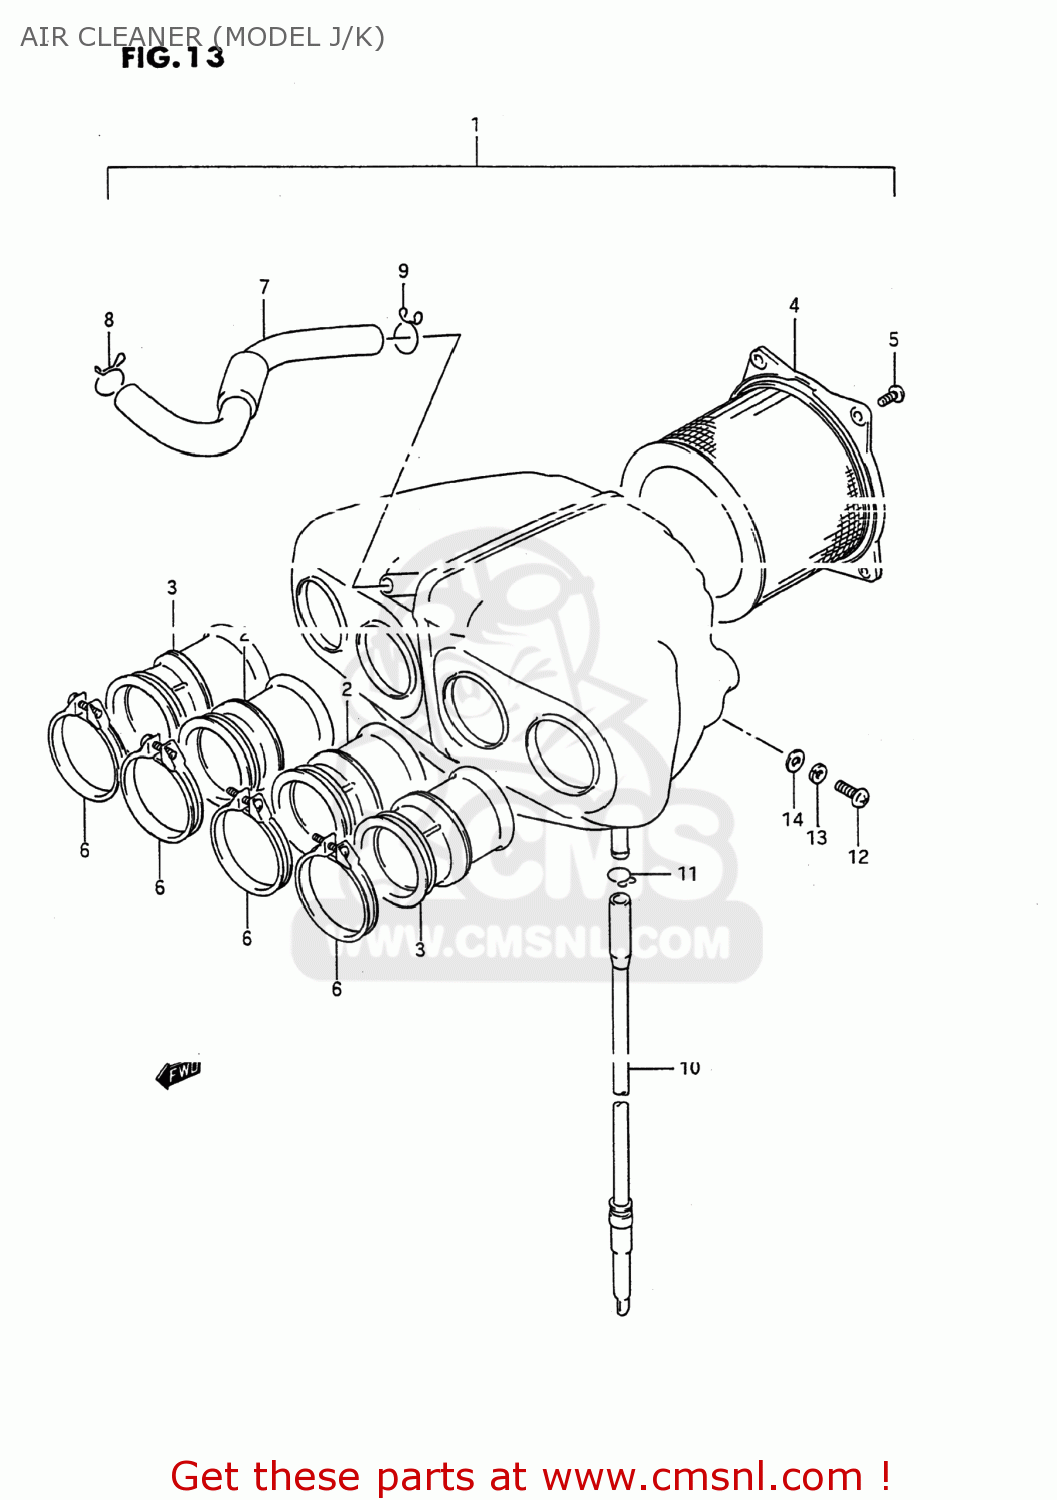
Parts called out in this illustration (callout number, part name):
1	CLEANER ASSEMBLY,AIR
2	TUBE,OUTLET NO.1
3	TUBE,OUTLET NO.2
4	FILTER,AIR CLEANER
5	SCREW, FRONT & REAR
6	CLAMP
7	TUBE,BREATHER
8	CLIP
9	CLIP
10	DRAIN TUBE
11	CLIP
12	SCREW
13	WASHER,LOCK
14	WASHER
